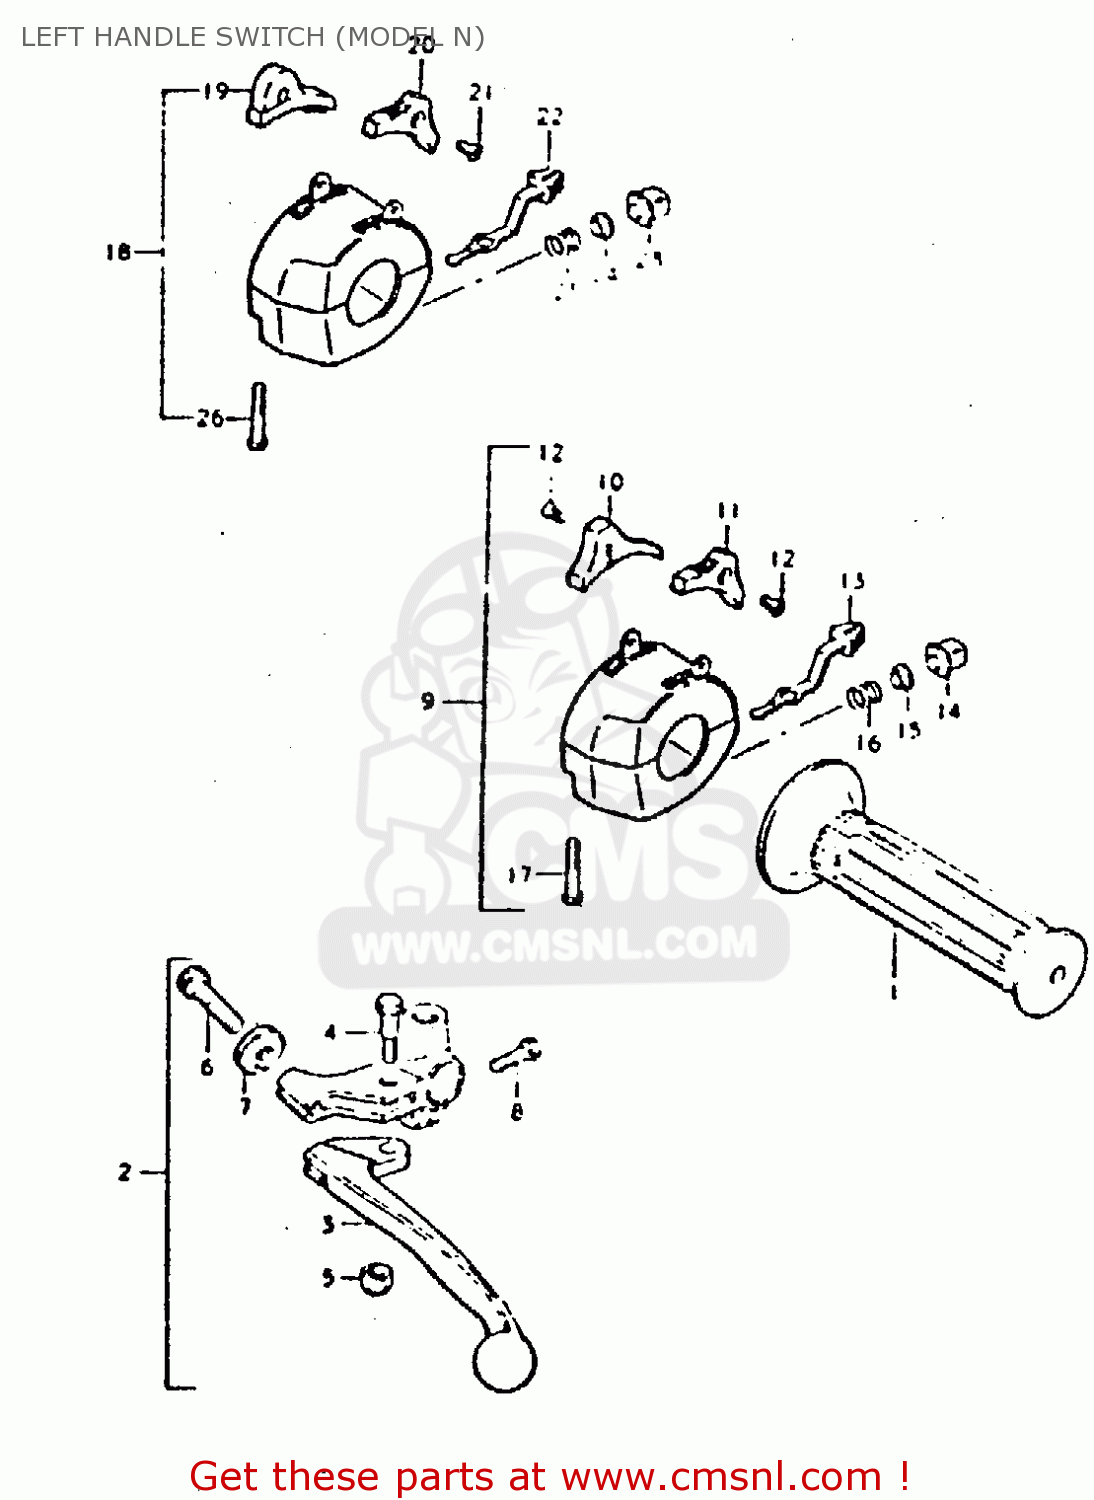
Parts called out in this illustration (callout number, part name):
1	GRIP,L
2	LEVER ASSEMBLY
3	LEVER,CLUTCH
4	BOLT,LEVER
5	NUT 6MM
6	ADJUSTER,CABLE
7	NUT,CABLE ADJUSTER
8	BOLT
9	SWITCH ASSY,HANDLE,L
10	KNOB,LIGHTING SWITCH
11	KNOB,DIMMER SWITCH
12	SCREW
13	KNOB,TURNSIGNAL
14	BUTTON,HORN
15	CONTACT
16	SPRING
17	SCREW
